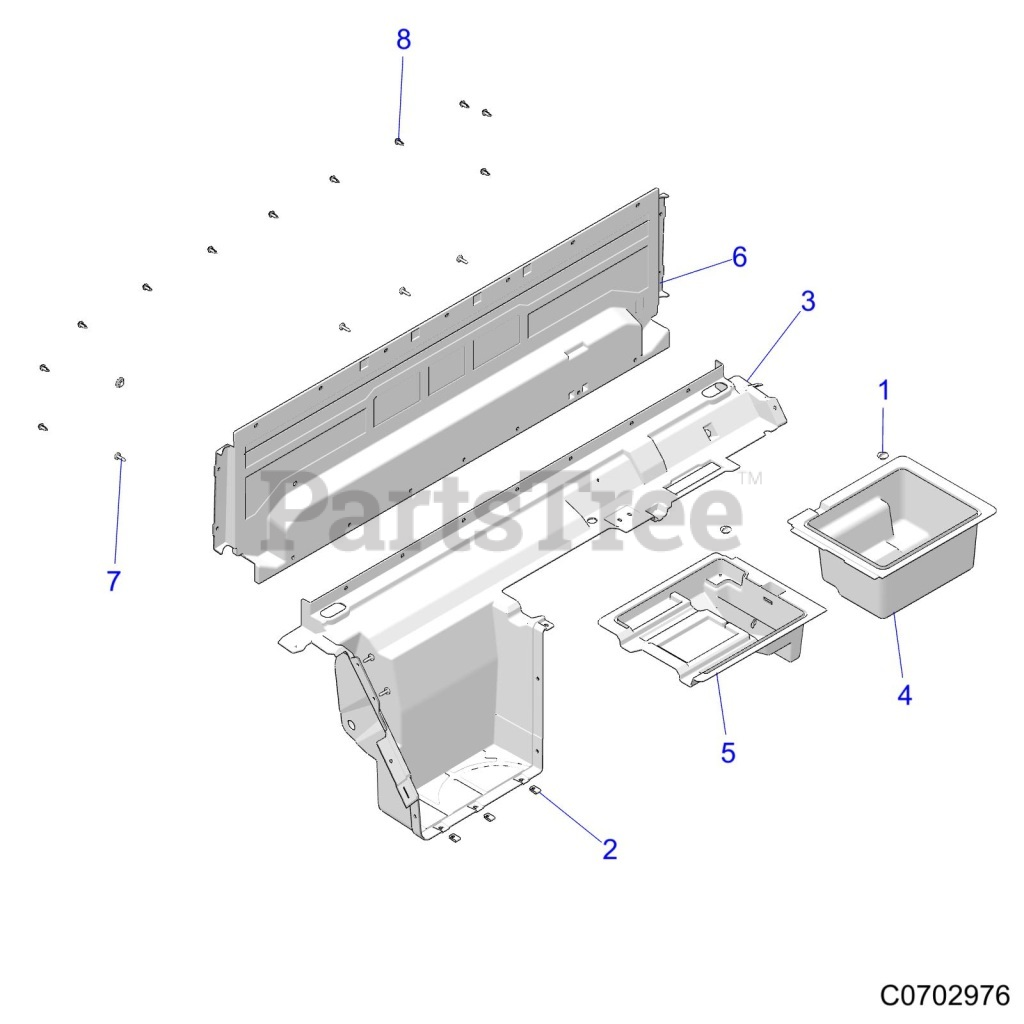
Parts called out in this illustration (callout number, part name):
1	PLUG-COMPARTMENT
2	NUT-M6-1.0,U-TYPE (2.5-3.8)
3	PANEL-CLOSEOFF,LOWER,BLK
4	BIN-STORAGE,LH,BLK
5	BIN-STORAGE,RH,BLK
6	PANEL-CLOSEOFF,REAR,BLK
7	SCR-TXTH-M6X1.0X25 RIE
8	RIVET-TUFLOK,.315-.325X.787 (5
